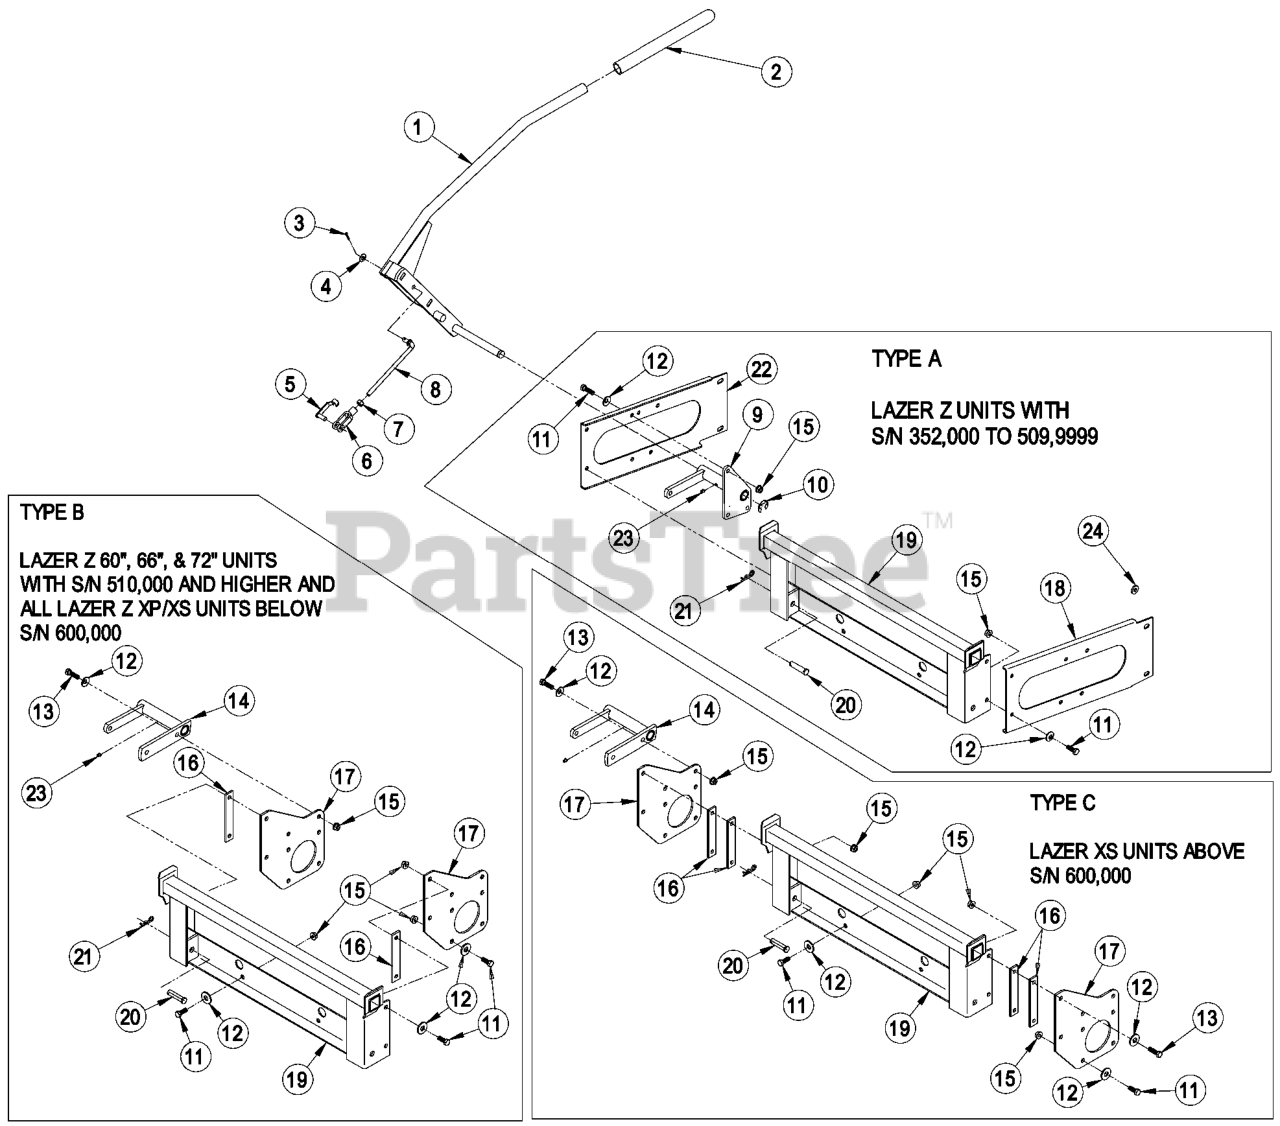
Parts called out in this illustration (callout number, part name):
1	HANDLE AND GRIP ASM
2	GRIP-HANDLE
3	PIN-COTTER
4	WASHER-FLAT
5	PIN-SPRING, CLEVIS
6	YOKE-LINKAGE, BRAKE
7	NUT-HEX
8	LINK-HANDLE
9	WLD, HANDLE MOUNT
11	SCREW-HH
12	WASHER-BELLEVILLE
13	SCREW-HH
14	WLD, HANDLE MOUNT - XP
15	NUT-HHF, WHIZ
16	SPACER
17	PLATE-MOUNT, BAGGER
18	BRACKET-FRAME, RH
19	MOUNT-BAGGER
20	PIN-CLEVIS
21	PIN-COTTER
22	BRACKET-FRAME, LH
23	FITTING-GREASE
24	SPACER
